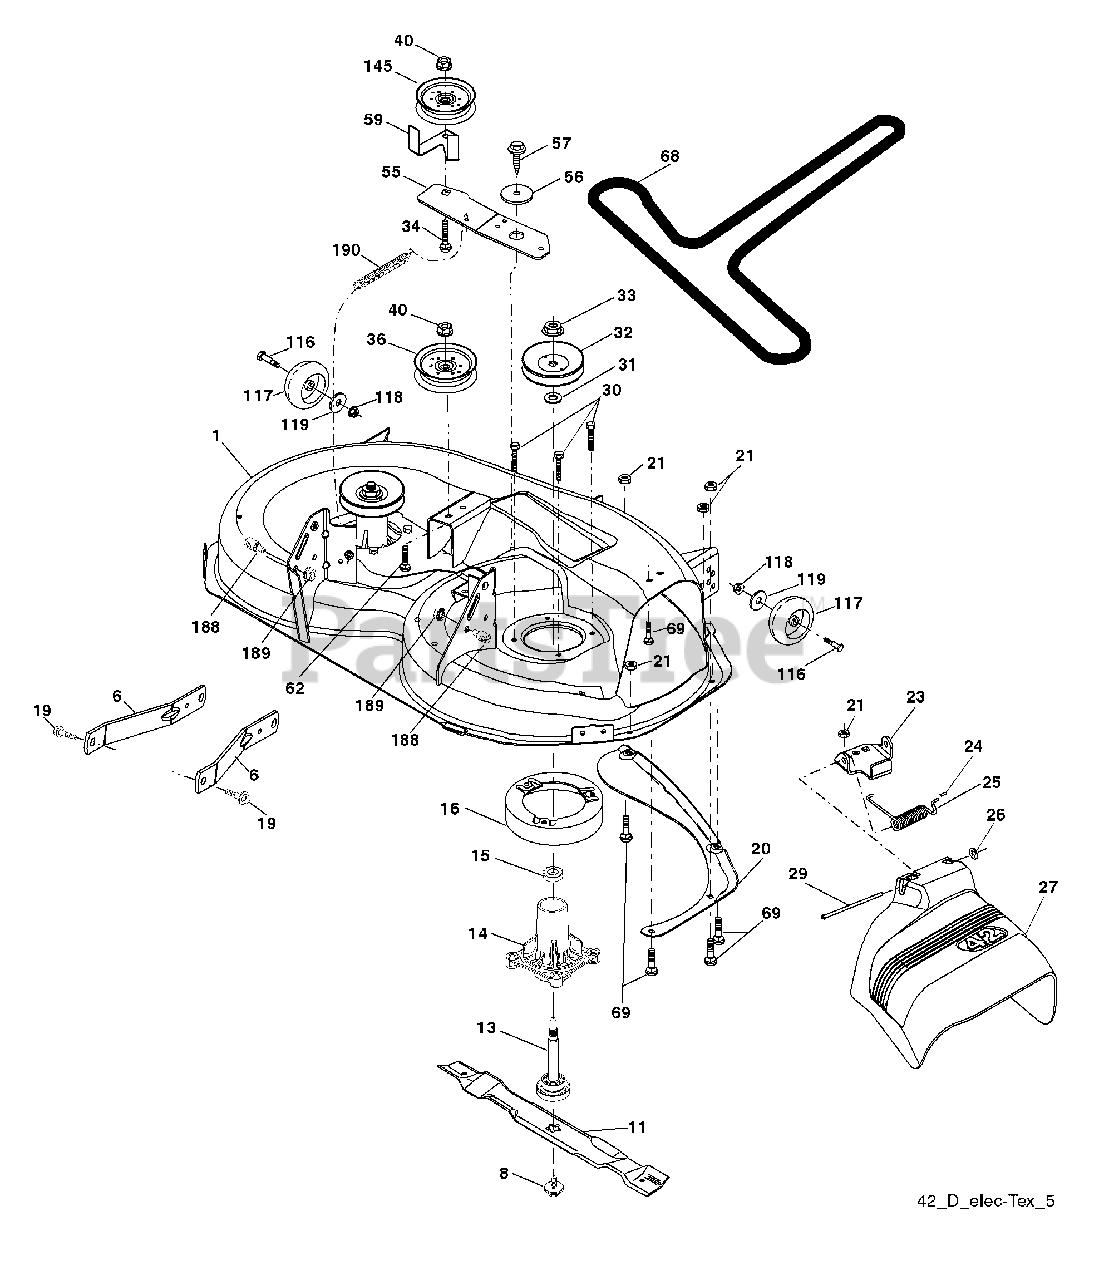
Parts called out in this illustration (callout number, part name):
1	Mower Housing
6	Arm Suspension
8	Bolt/Washer asm 7/16-20 unf
11	Blade, 42" Hi-Lift
11	Blade, 42" Mulching Std
11	Blade, 42" Mulching Premium
13	Shaft Assembly, Mandrel
14	Housing, Mandrel
15	Bearing, Ball, Mandrel
16	Stripper, Mower Deck
19	Bolt, Shoulder
20	Baffle, Vortex
21	Nut, Crownlock 5/16-18 unc
23	Bracket, Deflector
24	Cap, Sleeve
25	Spring, Torsion, Deflector
27	Shield, Deflector
29	Rod, Hinge
30	Screw Thdrol Rolling Wsh Hd
31	Washer, Spacer
32	Pulley, Mandrel
33	Nut, Toplock, Flanged
34	Bolt Carr Sh. 3/8-16 x 1-1/2 Gr. 5
36	Pulley, Idler, Flat
40	Nut, Lock Flg. 3/8-16 unc
55	Arm, Idler
56	Spacer, Retainer
57	Screw 3/8-16 x 1
59	Guard, Tuv Idler
62	Bolt Rd Hd Sq Nk 3/8-16 unc x 2
69	Bolt
116	Bolt, Shoulder
117	Wheel, Gauge
145	Pulley Idler
188	Stud Fastener
189	Nut Lock Hex Flange
190	Spring Mower Drive
196	Washer 13/32 x 1-1/4 x 12 Ga.
196	Mandrel Assembly
196	Replacement Mower, Complete
